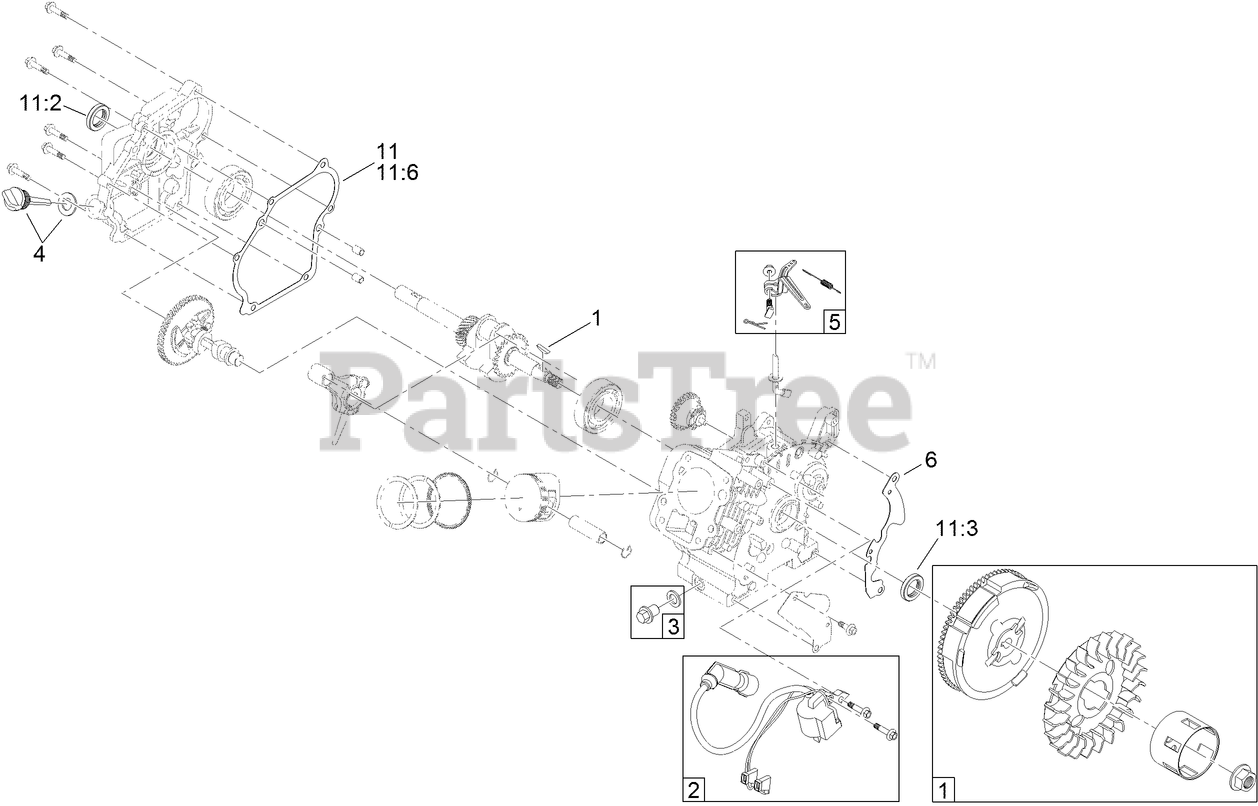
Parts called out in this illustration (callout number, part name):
1	FLYWHEEL AND FAN KIT
3	DRAIN PLUG KIT
4	DIPSTICK AND O-RING KIT
5	GOVERNOR KIT
6	BLOWER SHROUD KIT
11	GASKET, SEAL AND O-RING KIT
11:1	Gasket-Exhaust
11:2	Loose Parts Package
11:3	Loose Parts Package
11:4	GASKET-COVER, VALVE
11:5	GASKET-HEAD, CYLINDER
11:6	GASKET-COVER, CRANKCASE
11:7	GASKET-INSULATOR
11:8	INSULATOR-CARBURETOR
11:9	GASKET-CARBURETOR
